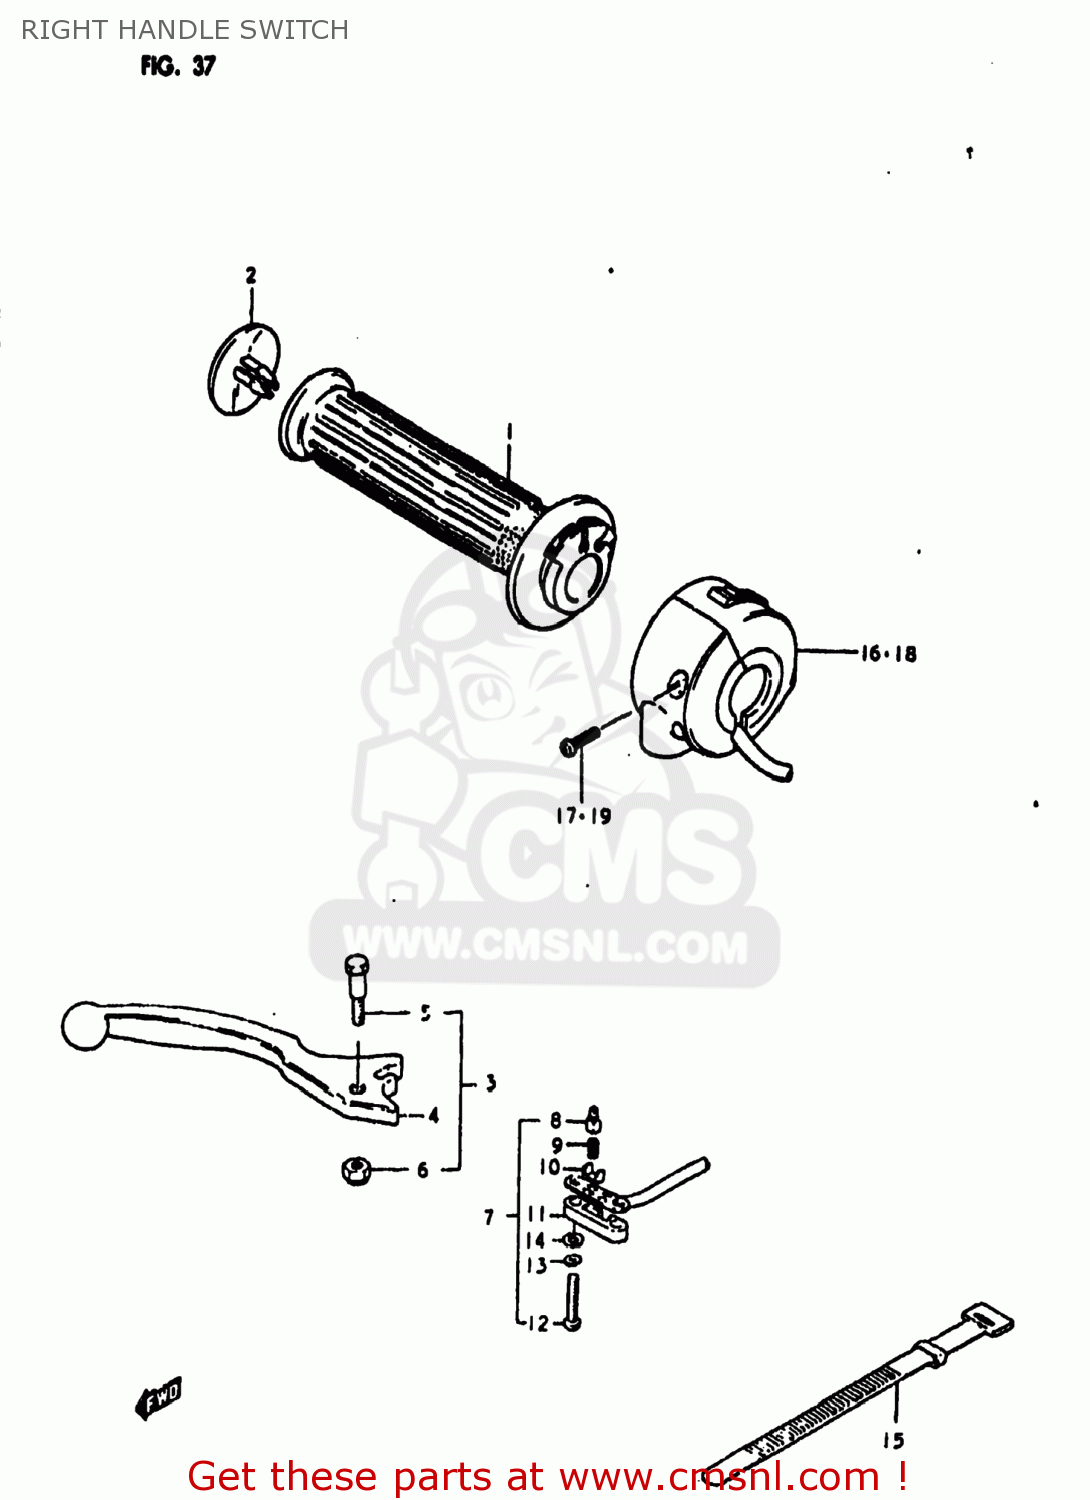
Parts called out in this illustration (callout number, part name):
1	GRIP,THROTTLE
2	CAP,GRIP END
3	LEVER ASSEMBLY,BRAKE
4	LEVER,BRAKE
5	BOLT
6	NUT 6MM
7	SWITCH ASSEMBLY
8	HOLDER
9	SPRING
10	PLATE
11	COVER,FR BK TERMINAL BASE
12	SCREW
13	LOCK WASHER
14	WASHER
15	CLAMP(L:120)
16	SWITCH ASSEMBLY,HANDLE,RIGHT
17	SCREW
18	SWITCH ASSEMBLY,HANDLE,RIGHT
19	SCREW
